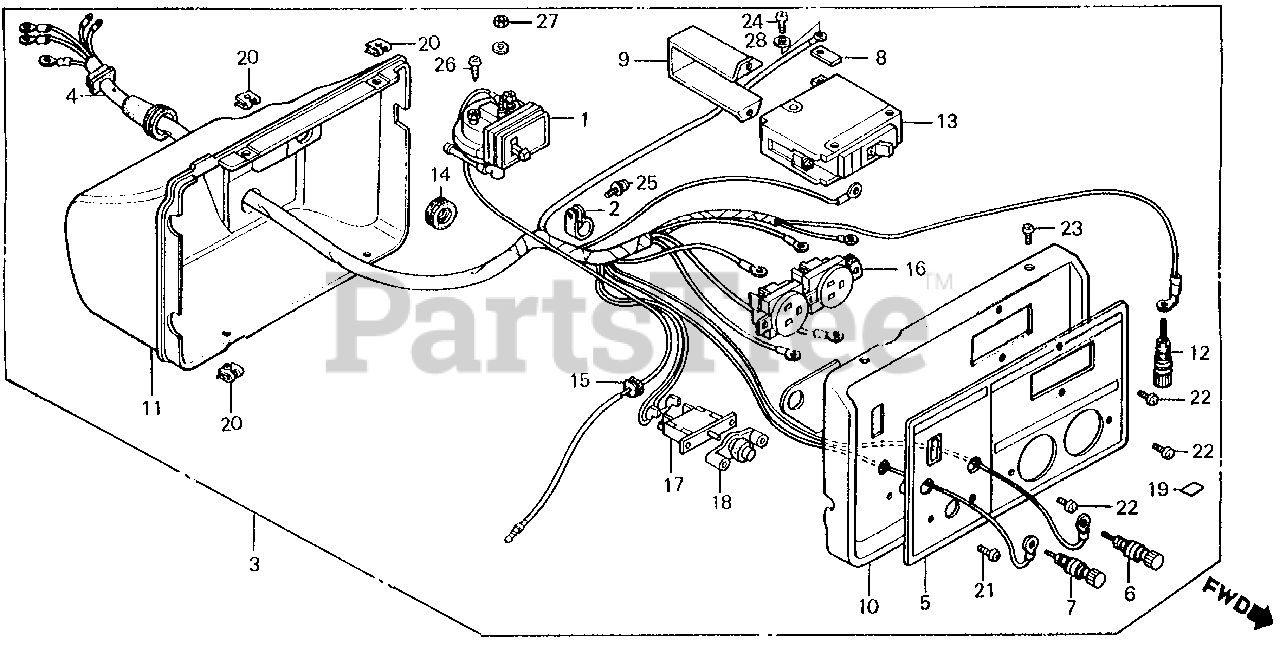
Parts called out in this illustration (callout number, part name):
1	SWITCH ASSY., UNIT
2	CLAMP, CABLE
3	BOX ASSY., CONTROL *R8* (BRIGHT RED)
4	WIRE HARNESS ASSY.
5	MARK, SWITCH PANEL
6	TERMINAL, D.C. OUT (+)
7	TERMINAL, D.C. OUT (-)
8	TERMINAL, BREAKER
9	SUPPORT, BREAKER
10	PANEL, CONTROL *R8* (BRIGHT RED)
11	CASE, CONTROL (NOT AVAILABLE)
12	TERMINAL ASSY., GROUND
13	BREAKER, CIRCUIT (15A)
14	GROMMET, UNIT SWITCH
15	GROMMET, SWITCH WIRE
16	RECEPTACLE (15A/125V)
17	PROTECTOR, CIRCUIT (DC)
18	LENS ASSY., PROTECTOR
19	MARK, GROUND
20	NUT, SPRING (5MM)
21	SCREW, PAN (3X12)
22	SCREW, PAN (4X6)
23	SCREW, PAN (5X12)
24	SCREW, PAN (5X12)
25	SCREW-WASHER (4X16)
26	SCREW, TAPPING (5X10)
27	NUT, HEX. (5MM)
28	WASHER, SPRING (5MM)
